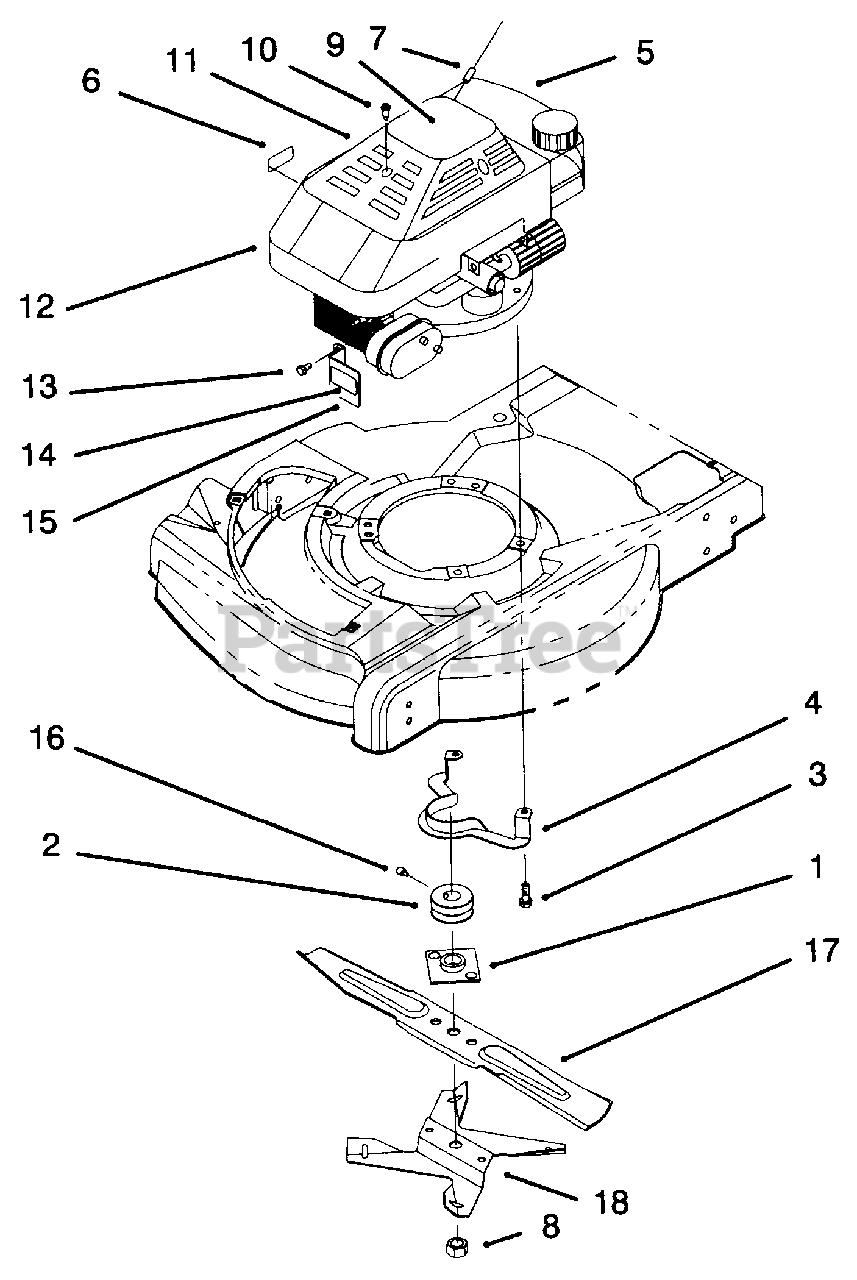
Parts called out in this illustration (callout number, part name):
1	Plate & Collar Assembly
2	Pulley-Engine
3	Screw-Engine
4	Guide-Belt
5	Engine
6	Decal-Oil Instruction
7	Rope-Stop
8	Nut-Blade
9	Decal-Recoil
10	Screw-Recoil Cover
11	Cover-Starter
12	Shroud-Engine
13	Screw-Hex Socket Hd.
14	Decal-Warning
15	Guard-Muffler (Incl. Ref. #14)
16	Screw-Set
17	Blade-21" Whirl
18	Fan-Mulching
